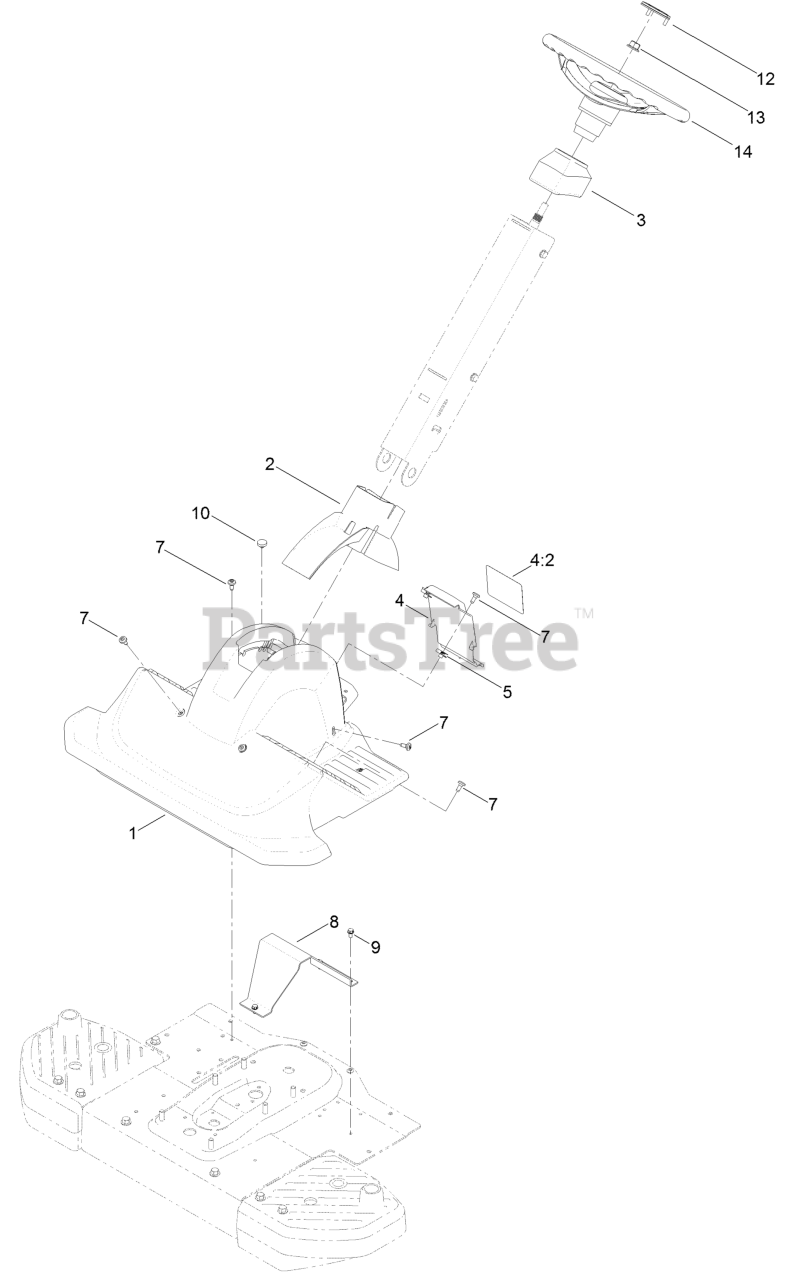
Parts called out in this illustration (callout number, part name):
1	Shroud-Styling, Front
2	COVER-PIVOT, COLUMN
3	CAP-COLUMN
4	REAR COVER AND DECAL ASM
4:2	DECAL-DANGER
5	Nut-Retainer-Panel 1/4-20
7	SCREW-SHOULDER
8	SUPPORT-FOOTREST
9	SCREW-HWH
12	CAP-WHEEL, STEERING
13	Nut-Lock 1/2-13
14	WHEEL-STEERING
